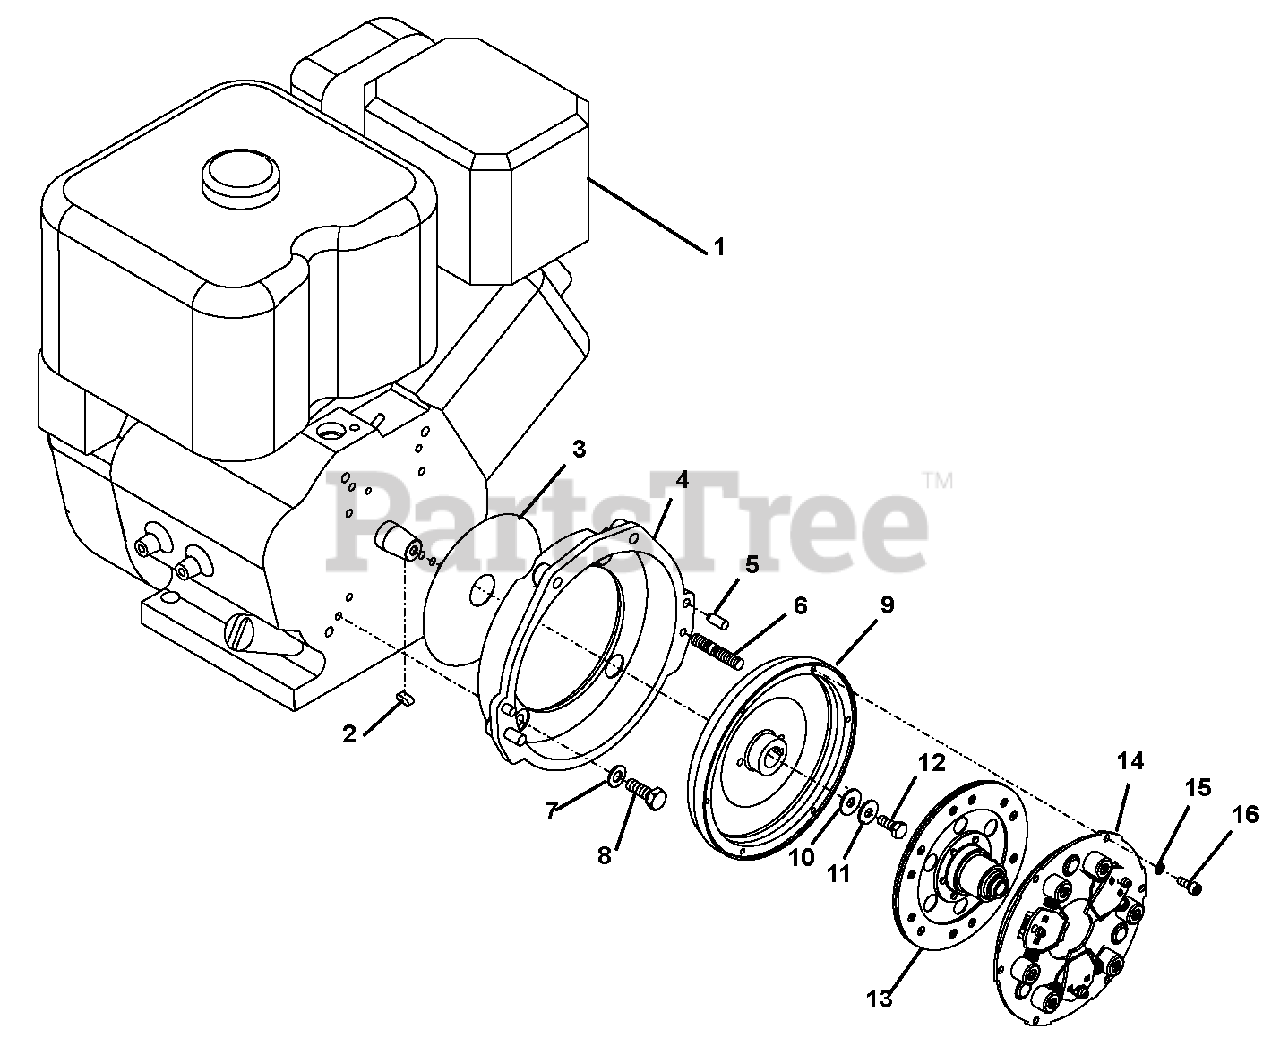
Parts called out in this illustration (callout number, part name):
1	Engine, Basco
2	Feather Key
3	Plate, Intermediate
4	Flange Engine
5	Straight Pin
6	Bolt, Stud
7	Washer, Form Steel 10.2/20.25 x 1.6
8	Bolt, Hex 3/8" x 1"
9	Flywheel
10	Washer, D440 9.5 x 28 x 3
11	Washer, M8
12	Bolt, Hex D933 M8 x 20
13	Disk, Clutch
14	Clutch Assembly
16	Screw, M6 x 14
